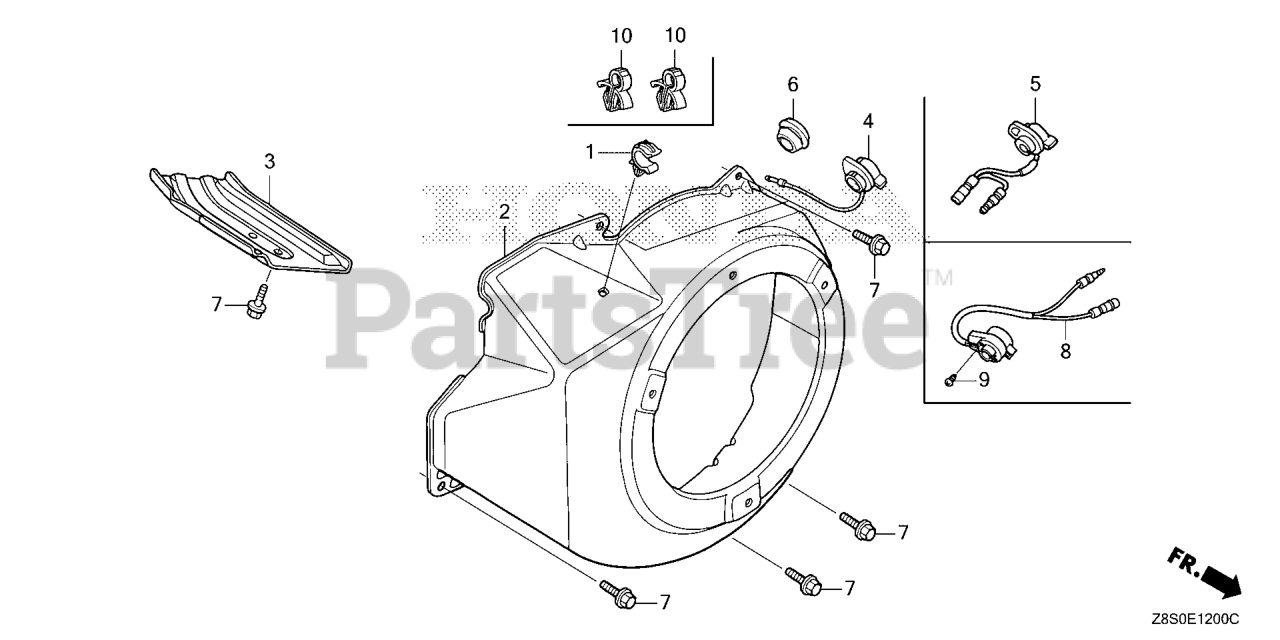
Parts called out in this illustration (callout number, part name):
1	CLIP, TUBE
2	COVER, FAN *NH1* (BLACK)
2	COVER, FAN *R280* (POWER RED)
6	GROMMET, DRAIN HOLE
7	BOLT, FLANGE (6X12) (CT200)
